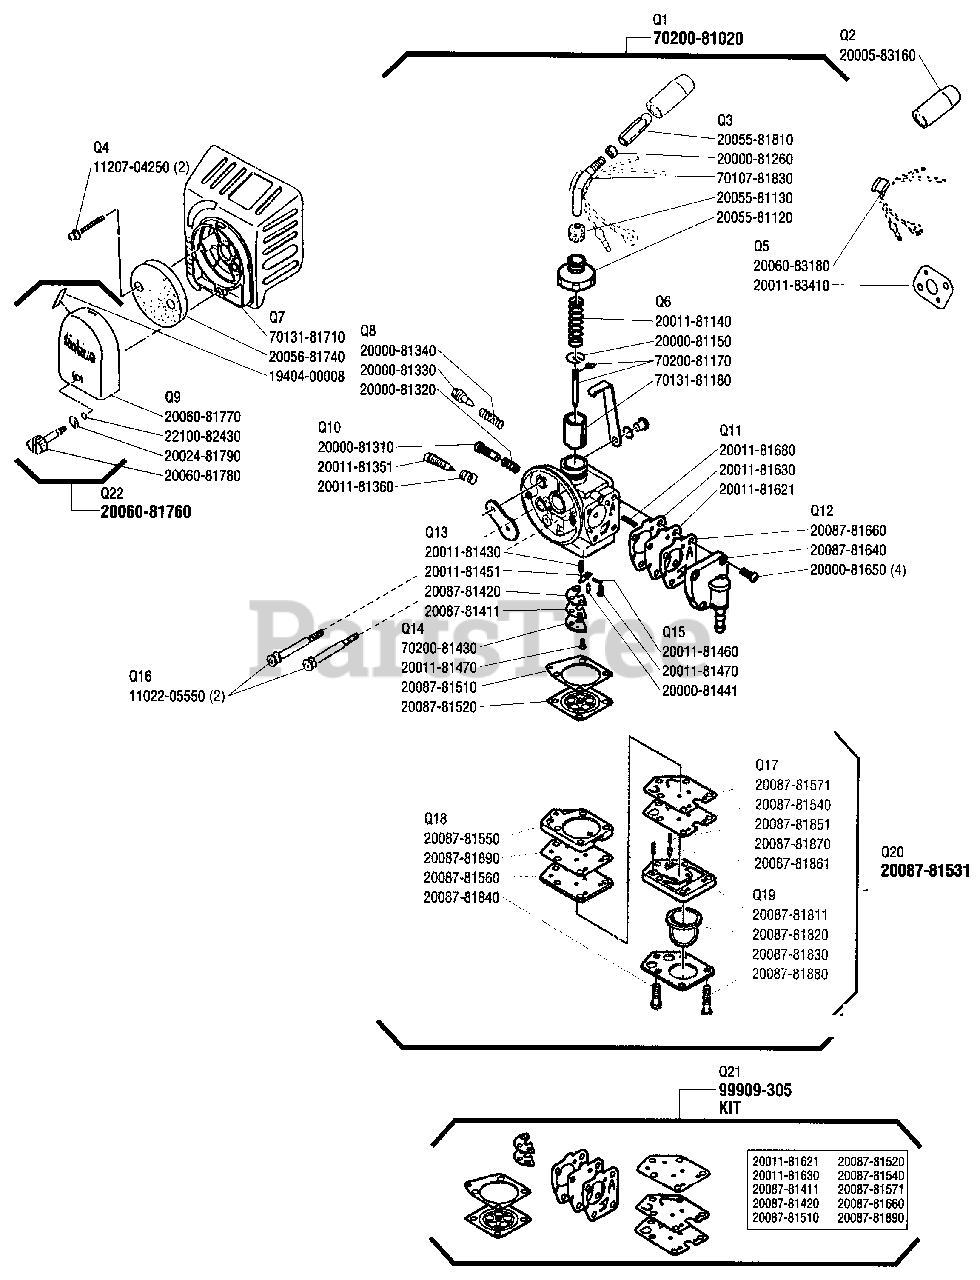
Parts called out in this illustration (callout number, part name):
Q1	CARBURETOR
Q2	CAP, DUST
Q3	GUIDE, CABLE
Q3	LOCKNUT
Q3	CAP, CARBURETOR
Q3	GROMMET
Q3	NUT, CABLE ADJUST
Q4	SCREW - 4X25
Q5	TUBE
Q5	GASKET
Q6	RETAINER
Q6	SPRING
Q6	VALVE, THROTTLE
Q6	NEEDLE, JET
Q7	LABEL - CHOKE
Q7	FILTER, AIR
Q7	AIR FILTER CASE ASSY
Q8	SPRING
Q8	SCREW, SLOW AIR
Q9	KNOB
Q9	WASHER - CONICAL
Q9	COVER, AIR FILTER
Q9	O-RING
Q10	SCREW, IDLE ADJUST
Q11	SPRING
Q11	DIAPHRAGM, METERING
Q11	GASKET, METERING
Q12	SCREW
Q12	BODY, PUMP
Q12	VALVE, PUMP
Q13	SPRING
Q13	LEVER, METERING
Q13	VALVE, CHECK
Q13	GASKET
Q14	SCREW, METERING LEVER PIN
Q14	GASKET, METERING
Q14	DIAPHRAGM, METERING
Q14	PLATE
Q15	SCREW, METERING LEVER PIN
Q15	VALVE, INLET NEEDLE
Q15	PIN, METERING LEVER
Q16	SCREW - 5X50
Q17	GASKET
Q17	DIAPHRAGM
Q17	SPRING, RETURN
Q17	VALVE
Q17	SPRING
Q18	BASE, PURGE
Q18	PLATE, PUMP
Q18	SCREW
Q18	GASKET
Q19	COVER, PUMP
Q19	BULB, PURGE
Q19	PLATE
Q19	SCREW
Q20	PRIMER PUMP ASSY
Q21	DIAPHRAGM/GASKET KIT
Q22	AIR FILTER COVER ASSY
